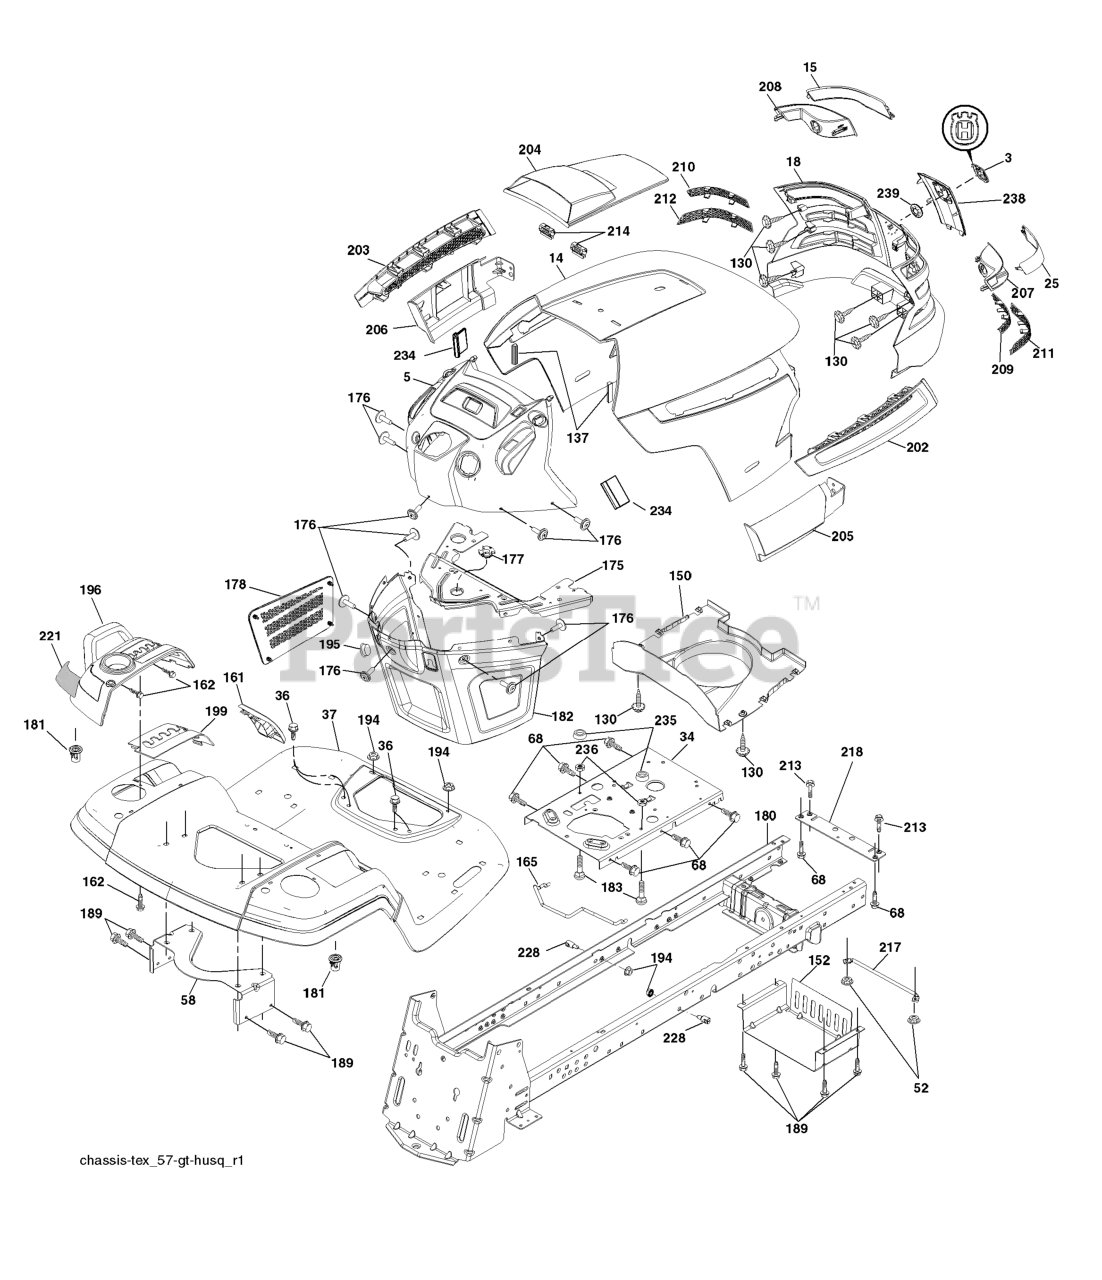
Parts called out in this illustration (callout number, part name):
3	RP LOGO
5	DASH.ASM.HUSQ.GT.E.RECT.W/CK
14	HOOD
15	LENS.LH.TEX.GT.HUSQ.CL
18	GRILL.ASM.HUSQ.TG/CRD.W/TRIM
25	LENS.RH.TEX.GT.HUSQ.CL
34	PLATE.ENGINE.WELDED.CHASSIS
36	SCREW 5/16"
37	FENDER.PNT.TX.GT.CH/FW.ORANGE
52	LOCKNUT
58	BRKT.SUPPORT.FNDR/TANK
68	Screw 5/16-18 x 1/2
130	SCREW.#10 X 0.750.BOS
137	BUMPER DASH
150	AIR.DUCT.HOOD.TEX.GT.HUSQ
152	SHIELD.BROWNING.W/TEX
161	CONSOLE.FUEL.WINDOW.HU
162	SCREW.HI-LO.CONSOLE
165	SUPPORT.TANK.REAR.W/TEX
175	PLATE.CROSSMEMBER.HUSQ
176	SCREW.#10-24X5/8.RN.QU
177	BUSHING, STEERING
178	CARGO.ASM.NET.TXGT.W/C
180	CHASSIS.GT.SLOPED.DRAWBAR.
181	BUSHING.MNT.FEND.CRGO.
182	DASH.LOWER.COMMON.12V.ADAPTOR
183	BOLT.5/16-18X1-1/4 FULL.THREAD
189	SCREW
194	NUT LOCK HEX FLANGE 5/16-18
195	PLUG.N/CRUISE.COMMON.YT/GT.BLK
196	CONSOLE.ASM.DCKLFT.W/RF.HQ.DLR
199	PLATE.DECK.LIFT.HUSQVARNA.GT
202	VENT.SIDE.HOOD.HUSQ.RH.GREY
203	VENT.SIDE.HOOD.HUSQ.LH.GRAY
204	HOOD VENT
205	SKIRT.HOOD.SIDE.HUSQ.RH.GREY
206	SKIRT.HOOD.SIDE.HUSQ.LH.GREY
207	BEZEL.RH.TEX.GT.HUSQ
208	BEZEL.LH.TEX.GT.HUSQ
209	INSERT.HEX.GRILL.HUSQ.GREY
210	INSERT.HEX.GRILL.HUSQ.
211	INSERT.HEX.GRILL.HUSQ.
212	INSERT.HEX.GRILL.HUSQ.
213	BOLT
214	CLIP.RETAINER.TINNER.
217	ROD.PIVOT.HOOD
218	X-PIECE.HOOD.STOP.NON/
221	REFLECTOR.LH.TEX GT HU
228	STUD.FASTNER.W/ANTI-ROTATE
234	BUMPER.HOOD.TEX.HUSQVARNA
235	SPACER FENDER
236	NUT.CENTERLOCK.5/16-
238	TRIM.HUSQ.TG/CRD.SERVICE
239	NUT PUSH M
